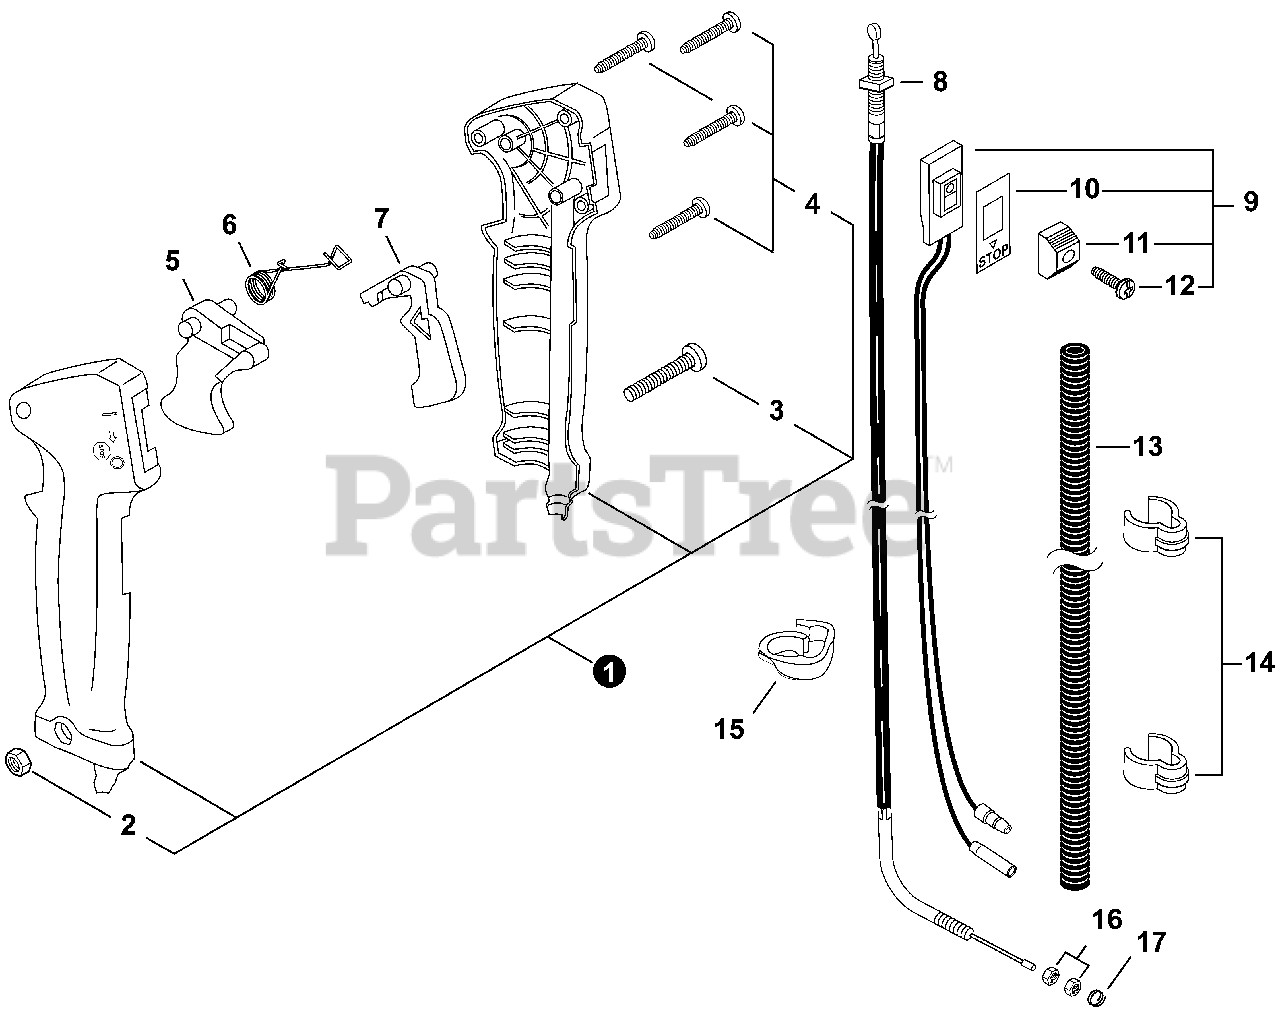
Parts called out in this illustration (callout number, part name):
1	CONTROL HANDLE KIT
3	SCREW 5×30
4	SCREW 3×25
5	TRIGGER, THROTTLE
6	SPRING, TORSION
7	LOCKOUT, THROTTLE
8	CABLE, THROTTLE
9	SWITCH, ON-OFF
10	LABEL, SWITCH
11	KNOB, SWITCH - ORANGE
12	SCREW 3×10
13	TUBE, FLEXIBLEIBLE 7×740
14	CLIP, CABLE 25 MM
